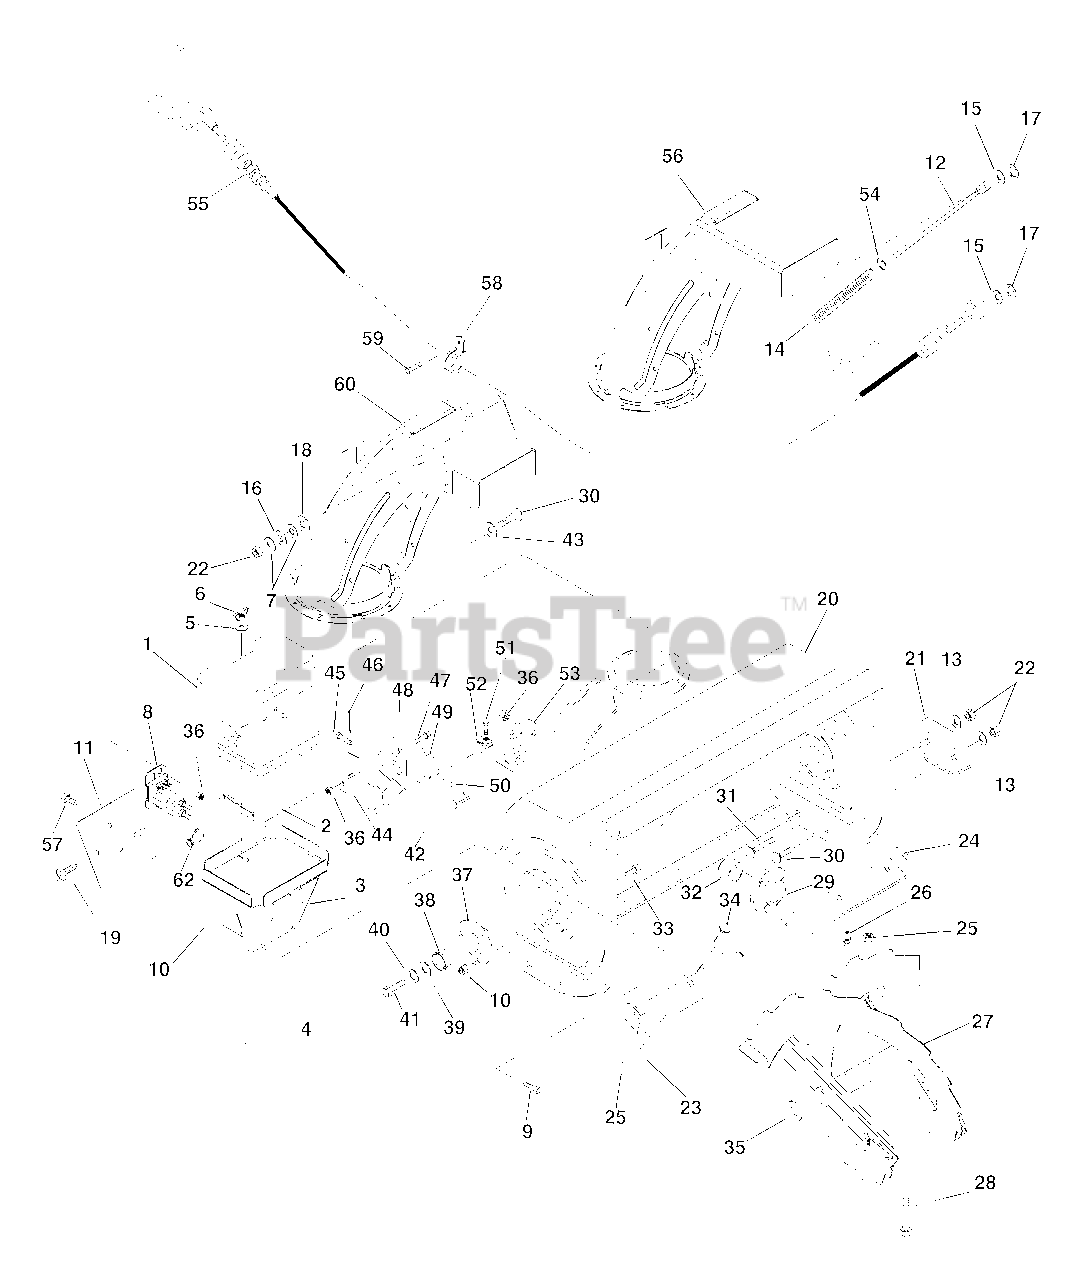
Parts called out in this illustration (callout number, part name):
1	COVER, BATTERY
2	Battery
3	TRAY, BATTERY - (36")
3	TRAY, BATTERY
4	@BLT-RDHDSQNK .25-20X7.00 G2YZ
5	@WSHR-FL-STL.281X.62X.065 YWZC
6	NUT-LK WING .250-20 YWZC
7	@WSHR-FL-STL.406X.812X.065 YWZ
8	SOLENOID
9	@BLT-HEX .25-20X.75 GR5 YWZC
10	@NUT-SPNLK-FLG .25-20 YWZC
11	COVER, SOLENOID
12	ROD, CHUTE
13	@WSHR-FL-STL.438X1.00X.083 YWZ
14	SPRING, COMP. .08 X .40 X 7.15
15	@WSHR-FL-STL.281X.62X.065 YWZC
16	WAVE WASHER .390X.655X.110
17	RG-RTNG-EXT .218X.035 TYPE E
18	WSHR-PLASTIC .390X.875X.062
19	@SCR-TAP .25-20X.50 HWH TR YWZ
20	HOUSING, 28" BLOWER
20	HOUSING, 24" BLOWER
20	HOUSING, 32" BLOWER
20	HOUSING, 36" BLOWER
21	RUNNER, SKID SHOE-1/2" FLANGE
21	SKID SHOE, REVERSIBLE - ORANGE
22	@NUT-LK-CTR .38-16 YWZC
23	@WSHR-FL-STL.38X.875X.083 YWZC
24	SCRAPER, BLADE 28"
24	SCRAPER BLADE 24"
24	BLADE, SCRAPPER - 28"
24	BLADE, 32" SCRAPPER
24	BLADE, SCRAPPER - 36"
25	@NUT-LK-CTR .31-18 YWZC
26	FTG-LUBE .25-28X.256 YWZC
27	RAKE, LEFT-28"(1"ID X 15.75OD)
27	RAKE, RIGHT-28"(1ID X 15.75OD)
27	RAKE, R.H.-24"(1 ID X 15.75OD)
27	RAKE, L.H.-24"(1 ID X 15.75OD)
27	RAKE, LEFT-28"(1"ID X 14.75OD)
27	RAKE, RIGHT-28"(1ID X 14.75OD)
27	RAKE, LEFT-32"(1"ID X 15.75OD)
27	RAKE, RIGHT-32"(1ID X 15.75OD)
27	RAKE, LEFT-36"(1"ID X 15.75OD)
27	RAKE, RIGHT-36"(1ID X 15.75OD)
28	SHEAR BOLT SERVICE ASSEMBLY
29	BEARING FLANGE
30	BLT-RHHDSQSHNK .38-16X.75 G2YZ
31	@BLT-RDHDSHSQNK.38-16X1.0 G5YZ
32	BRG-BALL1.0X2.0X.56
32	BRG-BALL .750X1.750X.50
33	BLT-SERNK SL .25-20X.50 YWZC
34	@BLT-RHDSSQNK .31-18X.62 G5YZ
35	WSHR-FL-STL 1.010X1.505X.062YZ
36	@NUT-LK-CTR .25-20 YWZC
37	BEARING SUPPORT
38	BSHG-FLG 1.000X1.12X.62X1.50BR
39	WSHR-FL-STL.511X1.441X.125 YWZ
40	WSHR-LK .500X.151 HVY YWZC
41	@BLT-HEX .50-13X1.00 GR5 YWZC
42	SG-TENS .062X.56X8.0 WLD 11
43	WSHR-FL-STL .52X.827X.062 YWZC
44	ARM EXTENSION
45	PIN-CLEV .371X1.16 YWZC
46	@PIN-CTR .06X.75 EXTPRSQCT YWZ
47	@BLT-HEX .25-20X.75 GR5 YWZC
48	BRAKE ARM ASSEMBLY
49	BRAKE LINING
50	RVT-TBLR .187X.437 RH ST PL
51	BLT-SERHFWH .38-16X.75 YWZC
52	NUT-RETNR .38-16 TINRMAN
53	BEARING FLANGE
54	@WSHR-FL-STL.344X.688X.065YWZC
55	CABLE, DEFLECTOR CONTROL
56	CHUTE, DISCHARGE W/REMOTE
57	@BLT-HEX .25-20X.50 GR5 YWZC
58	CLAMP, CUSHIONED STEEL
59	@BLT-HEX .38-16X.75 GR5 YWZC
60	CHUTE, DISCHARGE W/O REMOTE
61	@WSHR-LK .25X.062 REG YWZC
62	BOOT, EYELET TERMINAL
